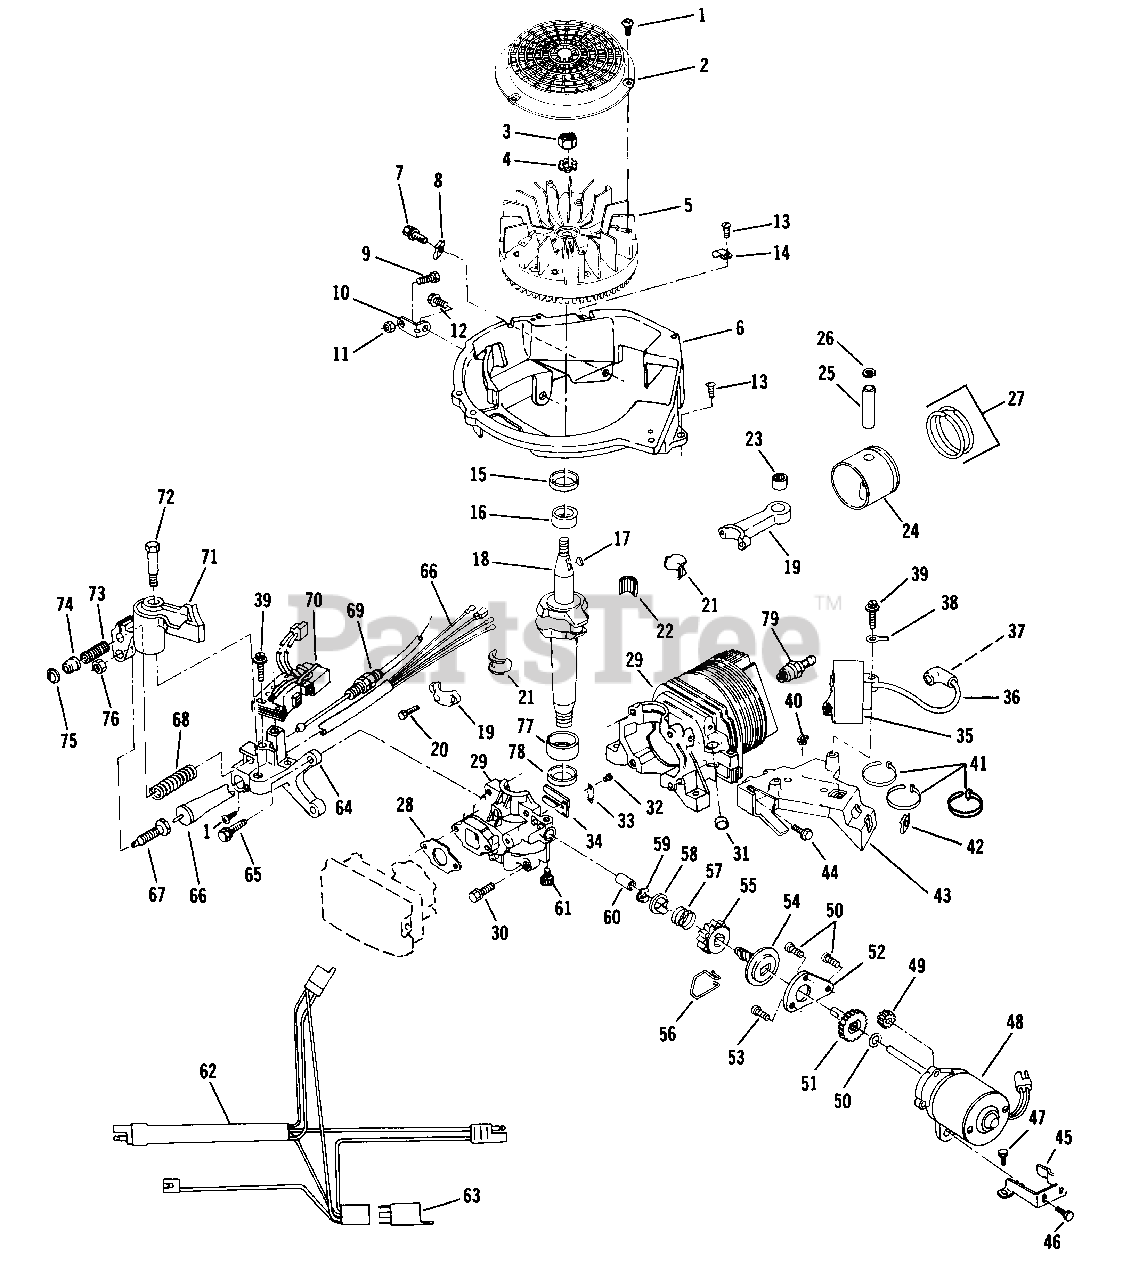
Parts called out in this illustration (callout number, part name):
1	Screw-Flywheel Screen and Switch
2	Screen-Flywheel
3	Nut-Flywheel
4	Lockwasher
5	Flywheel Assembly
6	Base-Shroud
8	Clip-"J"
9	Bolt-Brace-Alt. Brkt.
10	Brace-Alt. Bracket
11	Locknut-Brace-Alt. Brkt.
12	Screw
13	Screw-Shd. Base to C.D. Brkt. and Clamp to Shd. B.
15	Oil Seal-Upper
16	Bearing-Upper
17	Key-Flywheel
18	Crankshaft
19	Conn. Rod Assembly
20	Screw-Cap
21	Liner-Split
22	Needle Bearing Set
23	Bearing Assembly
24	Piston and Ring Assembly
25	Wrist Pin
26	Retaining Ring
27	Ring Set
28	Gasket-Carb. to Crankcase Cover
29	Cyl. and Crankcase Cov. Ass'y.
30	Screw-Cover to Crankcase
32	Screw-Reed to C'case Cover
33	Plate-Reed Hold Down
35	C.D. Ignition Module and Lead Assembly
36	High Tension Lead
37	Spring Terminal
38	Terminal-Ground Lead
39	Screw-C.D. Mtg. and Alt. Mounting
40	Grommet-C.D. Brkt.
41	Tie Strap
42	Clip-"U"
43	Bracket-Ign. Mounting
44	Screw
45	Bracket-Starter Mtg.
48	Mtr. Hsg. and Pin Assembly
49	Pinion-Motorshaft
50	Washer
51	Gear Driven
52	Plate-Gear Cover
54	Pinion, Spring and Clutch Ass'y.
56	Spring-Drag
57	Spring-Pinion Return
58	Washer-Pinion Stop
59	Retaining Ring
61	Set Screw-Starter Assembly
62	Wire Harness Assembly
64	Bracket-Alt. and Brk. Mtg.
65	Screw-Alt. and Brake Mtg. Brkt.
66	Brake Switch Assembly
67	Plunger
68	Spring-Brake
69	Control Cable Assembly
70	Alternator Assembly
71	Brake Assembly
72	Bolt-Shoulder
73	Spring-Cable Retainer
74	Actuator-Brake Lever
75	Retainer
76	Nut
77	Bearing-Lower
78	Oil Seal-Lower
79	Spark Plug
